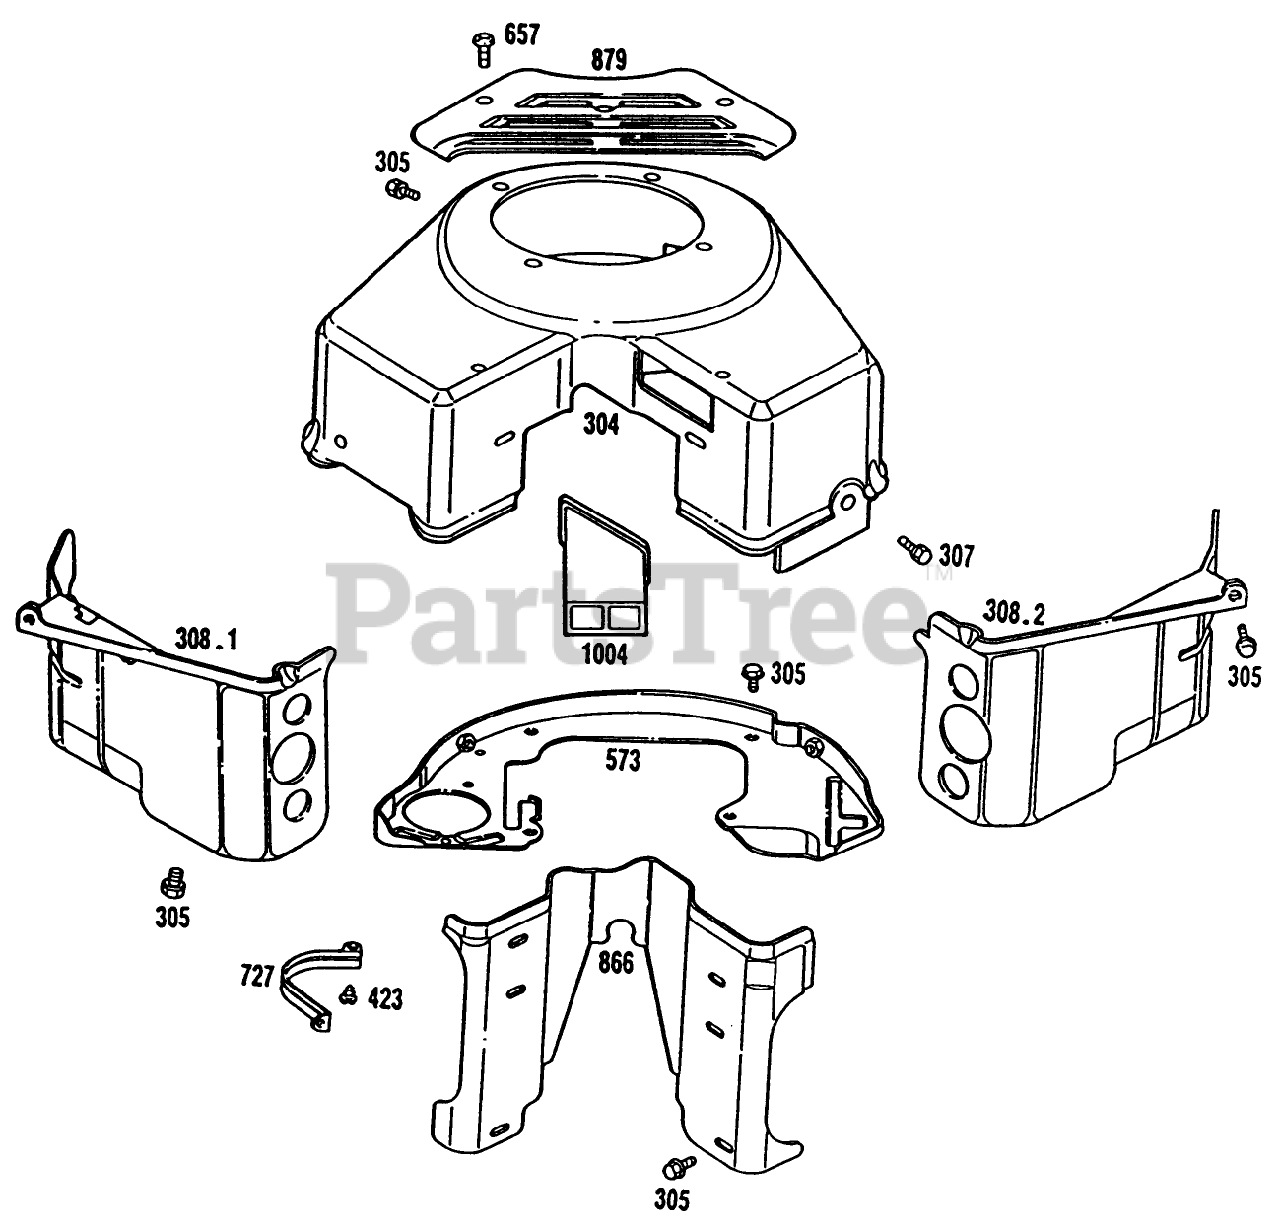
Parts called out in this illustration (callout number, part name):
305	BRIGGS 805406
307	BRIGGS-78-4310
308.1	BRIGGS-807656
423	BRIGGS-805260
573	BRIGGS 807663
657	BRIGGS 805009
727	BRIGGS-805505
1004	BRIGGS-805363
